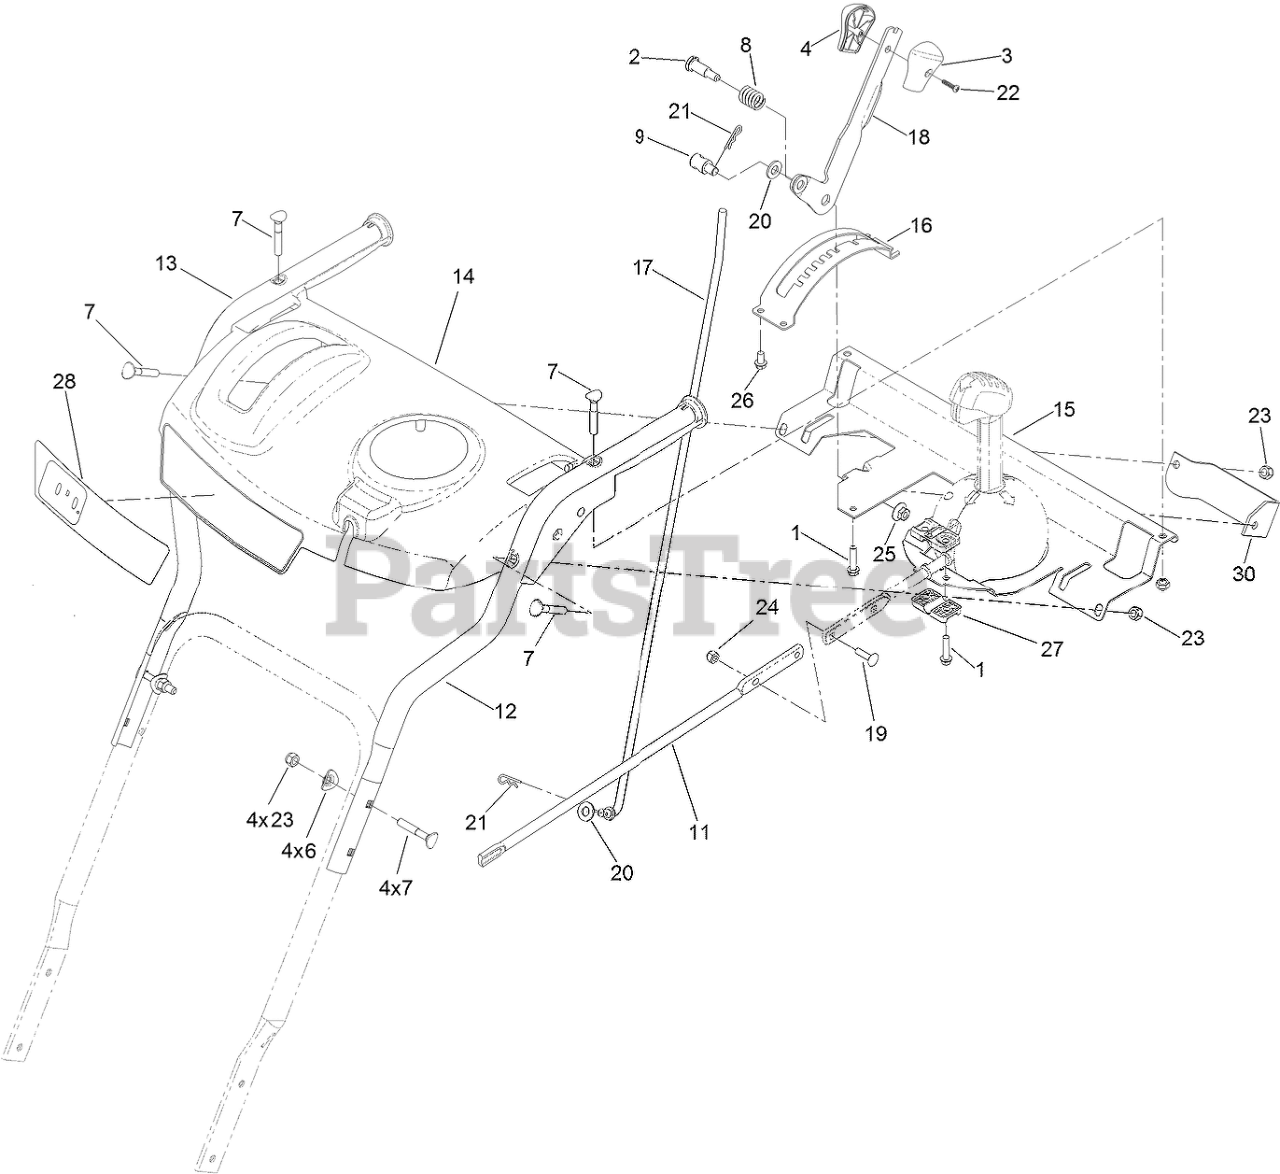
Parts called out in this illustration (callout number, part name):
1	SCREW-PLASTITE
2	SCREW-SHOULDER
3	KNOB-SHIFT, LH
4	KNOB-SHIFT, RH
6	WASHER
7	SCREW-HANDLE
8	SPRING-COMPRESSION
9	TRUNNION-ROD
11	ROD-CHUTE, FRONT
12	HANDLE-UPPER, LH
13	HANDLE-UPPER, RH
14	PANEL-CONTROL, MASTER
15	SUPPORT-PANEL, CONTROL
16	MOUNT-SELECTOR, SPEED
17	ROD-SELECTOR, GEAR
18	SELECTOR-SPEED
19	SCREW-CARR
20	WASHER-FLAT
21	PIN-COTTER
22	SCREW-PPH
23	NUT-LOCK, NI
24	NUT-LOCK, NI
25	NUT-HF
26	SCREW-PLASTITE
27	SUPPORT-ROD
28	DECAL-MODEL
30	PLATE-SUPPORT, SHIFT
